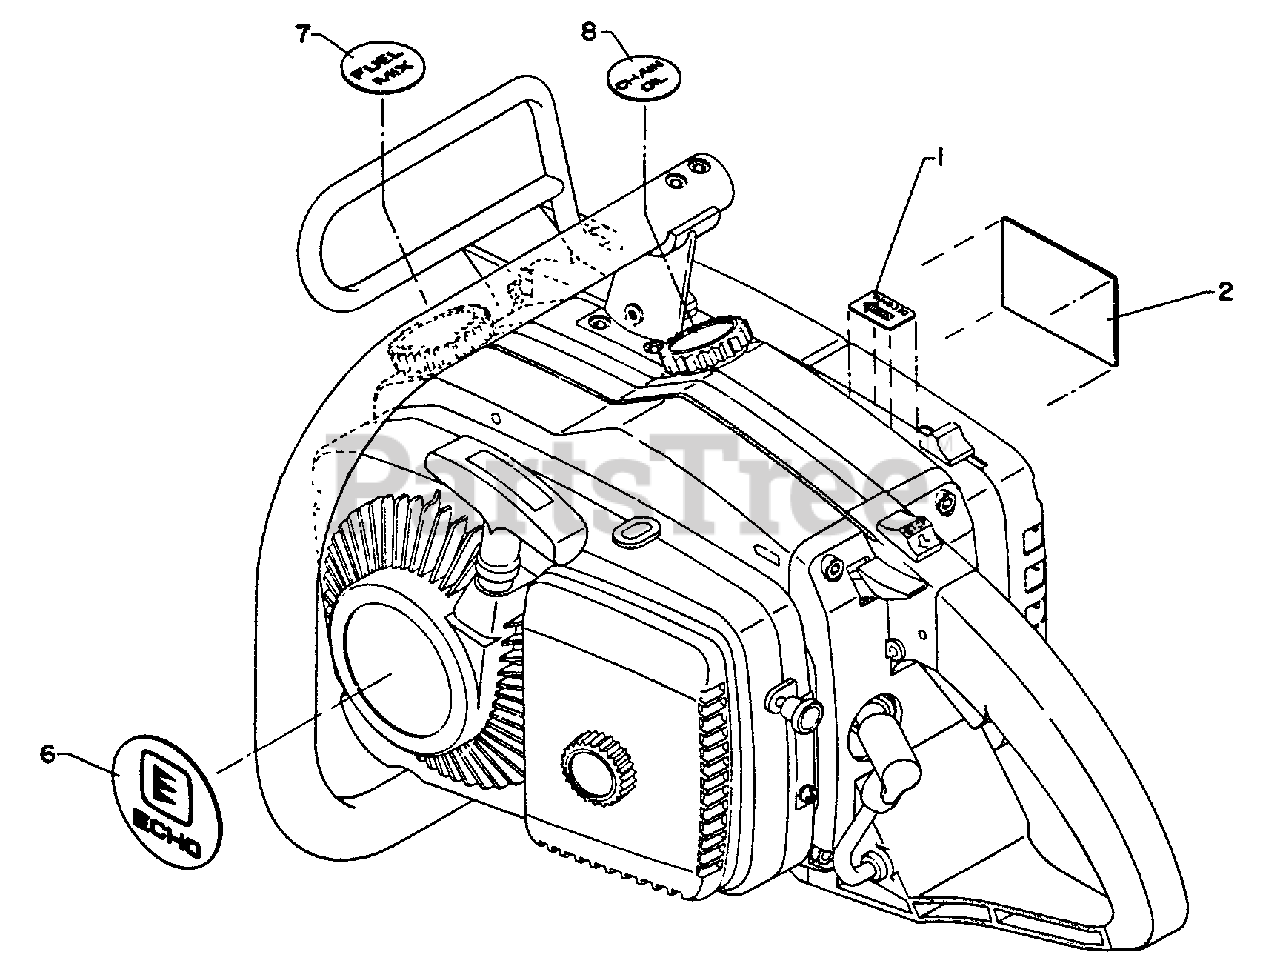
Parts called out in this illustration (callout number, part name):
1	LABEL - DECOMPRESSION
2	LABEL - ECHO
6	NAME PLATE
7	LABEL - FUEL MIX
8	LABEL - OIL
